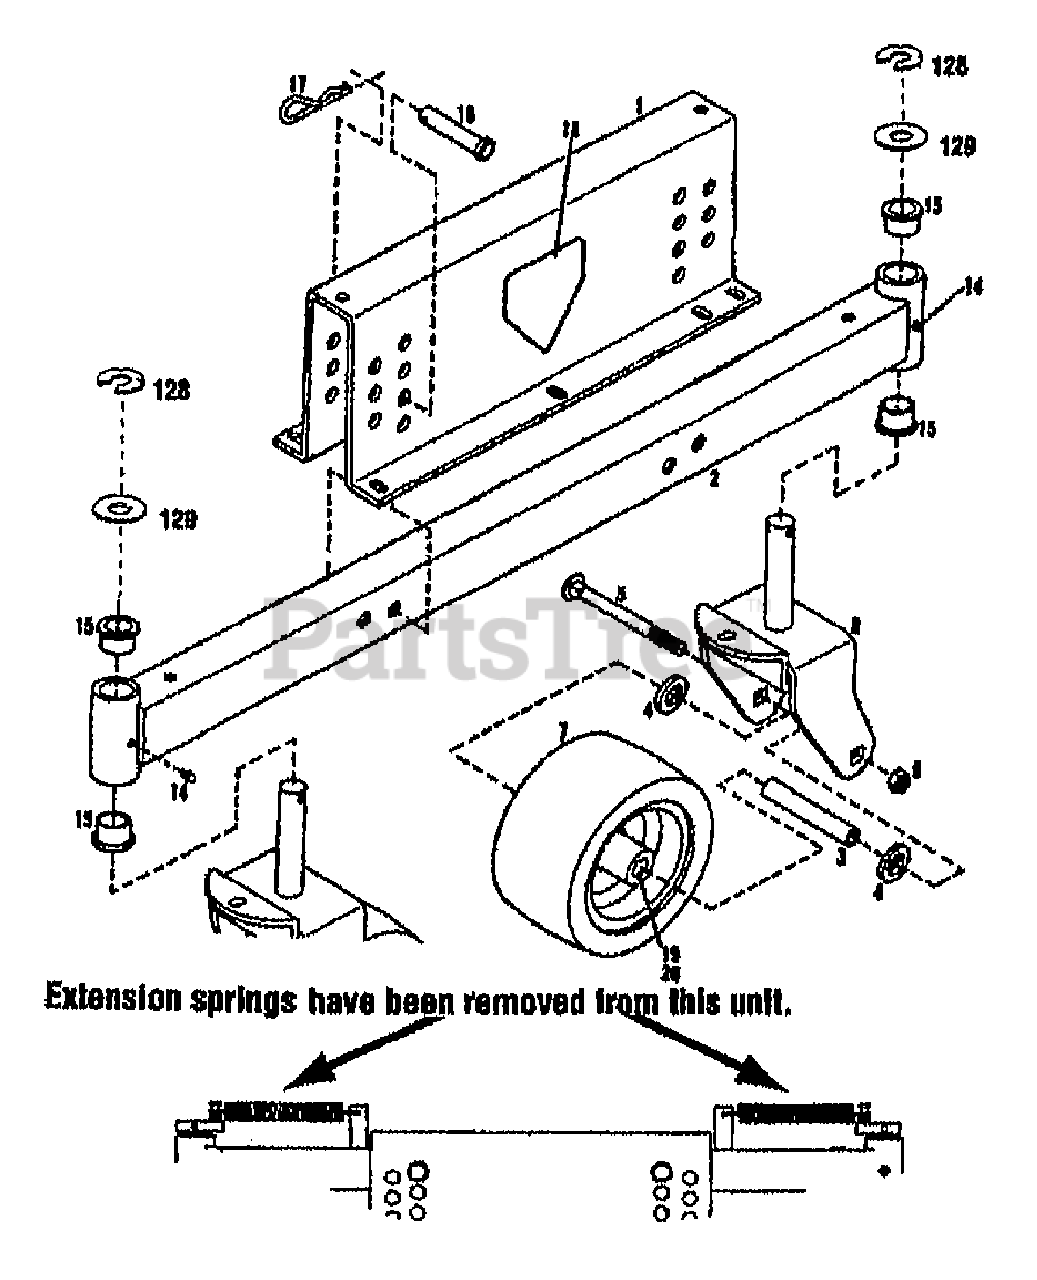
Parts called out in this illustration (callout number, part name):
1	Gage Wheel Mount w/Decals
2	Wheel Support Assembly
3	Wheel Sleeve
4	Flat Washer, 3/4
5	Carriage Bolt, 1/2-13 x 4-3/4
6	Top Lock Nut, 1/2-13
7	Wheel & Tire Assembly, 6.25 x 8.25
8	Wheel Yoke Assembly
14	Grease Fitting
15	Flange Bearing
16	Clovis Pin, 5/8 x 2-1/4
17	Hitch Pin
18	Decal, Danger
19	Roller Bearing
20	Bearing Cap
128	Retaining Ring
129	Washer
